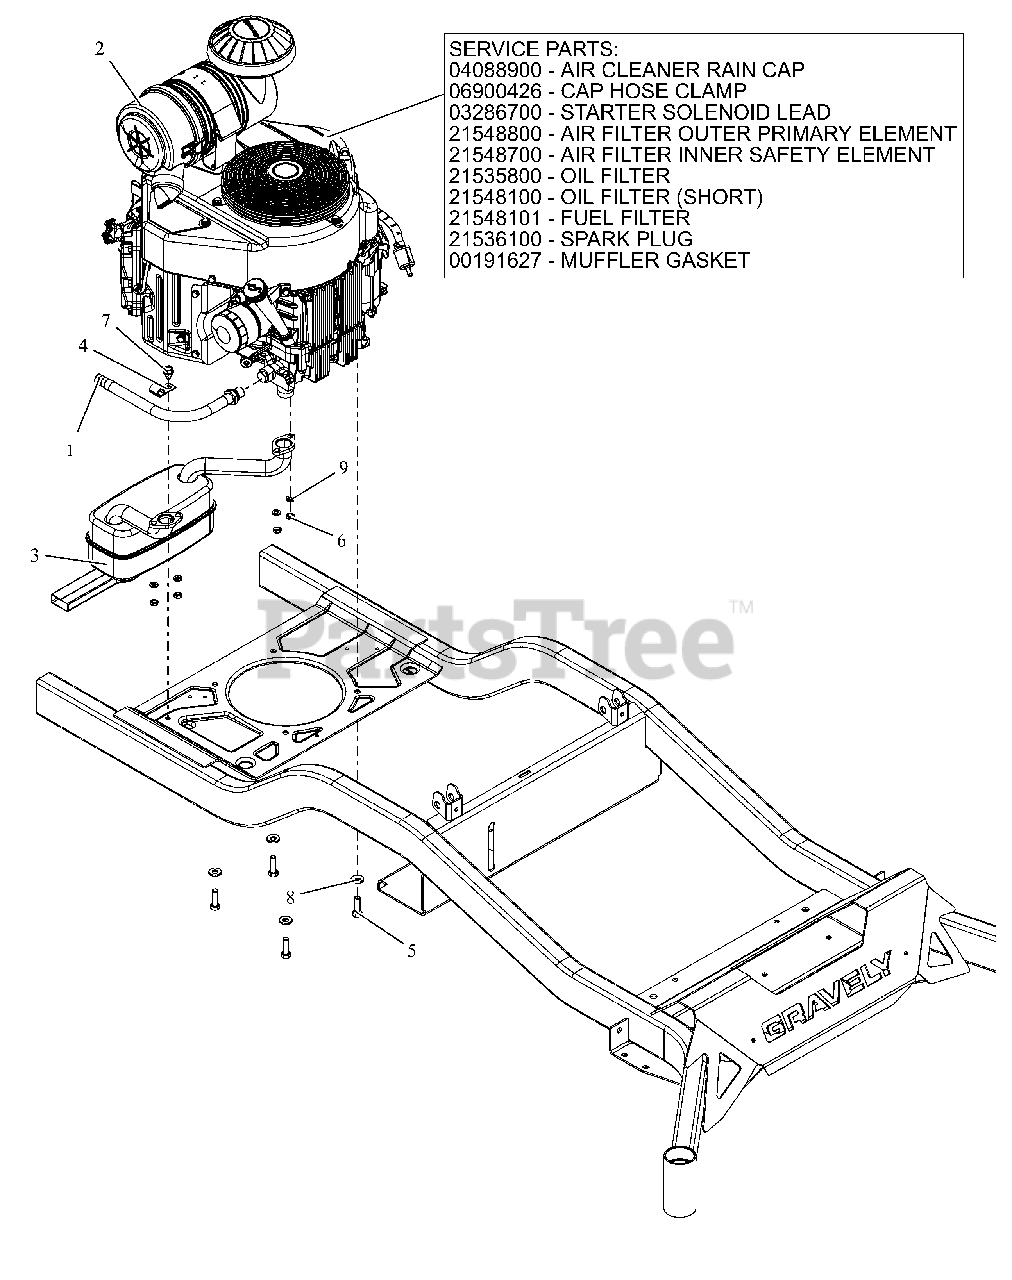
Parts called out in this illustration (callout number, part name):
1	HOSE, OIL DRAIN
2	ENGINE, KAWASAKI FX730
2	CAP, KAW 11065-7025
2	CLAMP, HOSE #36 SS 1.813-2.75
2	LEAD - STARTER SOLENOID
2	FILTER, OUTER
2	FILTER, INNER - KAW
2	FILTER,OIL - KAW
2	OIL FILTER, KAWASAKI FR
2	FUEL FILTER-KAWASAKI FR
2	PLUG, SPARK
2	GASKET, MUFFLER S/O
3	MUFFLER, KAWASAKI
5	BLT, HEX .38-16X1.25 G5 ZCC NT
6	NUT,NYL M8-1.25 G8.8 ZCC
7	SCR,TAP .375-16X.50 HWH TR ZCC
8	WASHER, 3/8" SPRING DISC
9	WSHR,LK-REG .312X.078 ZCC
